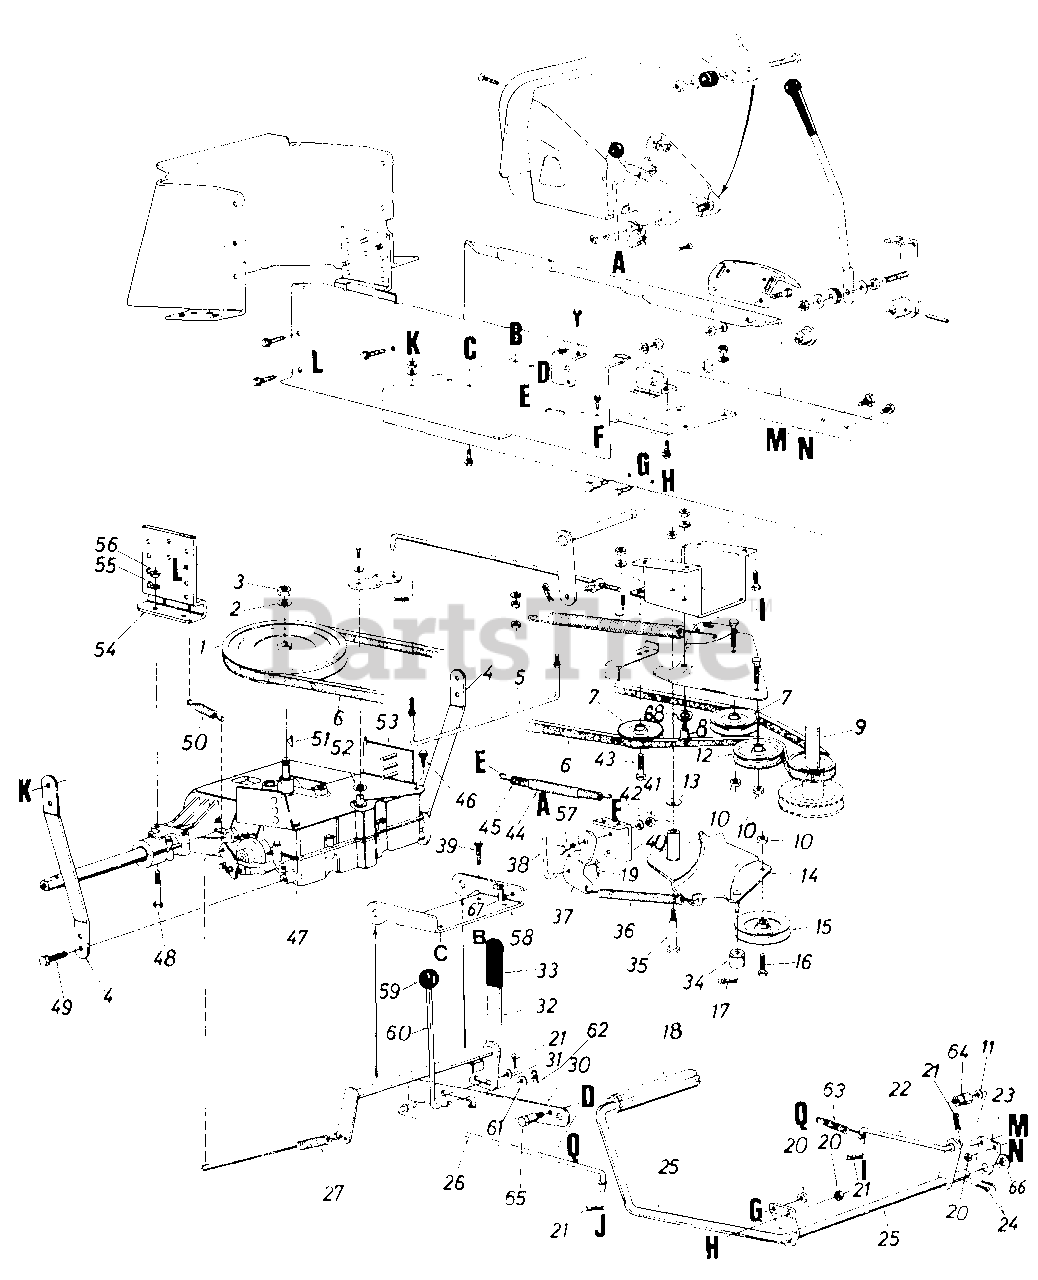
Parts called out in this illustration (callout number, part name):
1	8" "V"-Pulley
2	L-Wash. 1/2" I.D.
3	Hex Nut 1/2-20 Thd.
4	Transaxle Brace
5	Belt Guard
6	"V"-Belt
7	"V"-Belt Idler Pulley .38" I.D. x 3-1/16" O.D.
8	Shoulder Bolt .435" Dia. x .160 (5/16-18)
9	Two Step Engine Pulley 3.10" & 5.56" Dia.
10	Hex Cent. L-Nut 3/8-24 Thd.
11	L-Wash. 3/8" I.D.*
12	Flat Idler Pulley 2.75" O.D.
13	Belleville Wash. .400" I.D. x .88" O.D. x .063
14	Idler Bracket Ass'y.
15	4" "V"-ldler Pulley
16	Hex Bolt 3/8-24 x 1.5" Lg.
17	Hairpin Cotter 5/16" Dia.
18	Foot Pad
19	Intern. Cotter Pin 5/16n Dia.
20	Hex Cent. L-Nut 3/8-16 Thd.
21	Hairpin Cotter 3/32" Dia. x 3/4" Lg
22	Brake Clutch Rod (4.60" Lg.)
23	Clutch Rod Bearing Brkt.
24	Cotter Pin 1/8" Dia. x 1.00" Lg.*
25	Clutch Brake Pedal Ass'y.
26	Brake Cam Rod (13.60" Lg.)
27	Extension Spring .59" O.D. x.93" Lg.
30	Parking Brake Cam
31	Fl-Wash. .406" I.D. x 1.00" O.D. x .030 Thk.
32	Hand Brake Lever Ass'y.
33	Grip Flat Bar 11/4" Wide
34	Spacer
35	Shoulder Bolt .496" Dia. x 2.00n Lg. (3/8-16)
36	Extension Spring 75" O.D. x 6.12" Lg.
37	Deck Control Brkt.
38	Deck Control Rod
39	Hex Wash. Hd. TT-Tap Scr. 1/4-20 x 1.50" Lg.
40	Parking Brake Cam Mtg.Brkt.
41	Hex Nut 5/16-18 Thd.
42	L-Wash. 5/16" I.D.
43	Hex Bolt 3/8-24 x l.50n Lg. (Grade 5)
44	Convoluted Conduit 60" I.D. x 40n Lg
45	Ext. Spring 50" O.D. x 6 87" Lg.
46	Hex Wash. Hd. AB Tap Scr. 5/16-18 x 5/8" Lg.
47	Transaxle
48	Hex Bolt 5/16-18 x 2.50"Lg.
49	Hex Wash. Hd. AB Tap Scr. 5/16-18 x 618n Lg.
50	Extension Spring 50" O.D. x 2 75n Lg.
51	Hi-Pro Key 3/32" x 5/8" Dia.
52	Special Wash. 1.00" O.D. (Hdn .)
53	Transaxle Belt Keeper Ass'y.
54	Transaxle Support Bracket
55	L-Wash. 5/16n I.D.
56	Hex Nut 5/16-18 Thd.
57	Shoulder Bolt .435" Dia. x .162" Lg. (5/16-18)
58	Idle Mtg. Brkt.
59	Ball Knob
60	Parking Brake Link
61	Fl-Wash.
62	Hairpin Cotter
63	Ext. Spring 3.12" Lg.
64	Spacer Nut 3/8-16 Thd.
65	Shld. Bolt .435" Dia. x .162" Lg.
66	Fl-Wash. .53" I.D. x 93" O.D.
67	Plastic Hose Clamp
68	Spr. Wash. .445" I.D. x .75"
